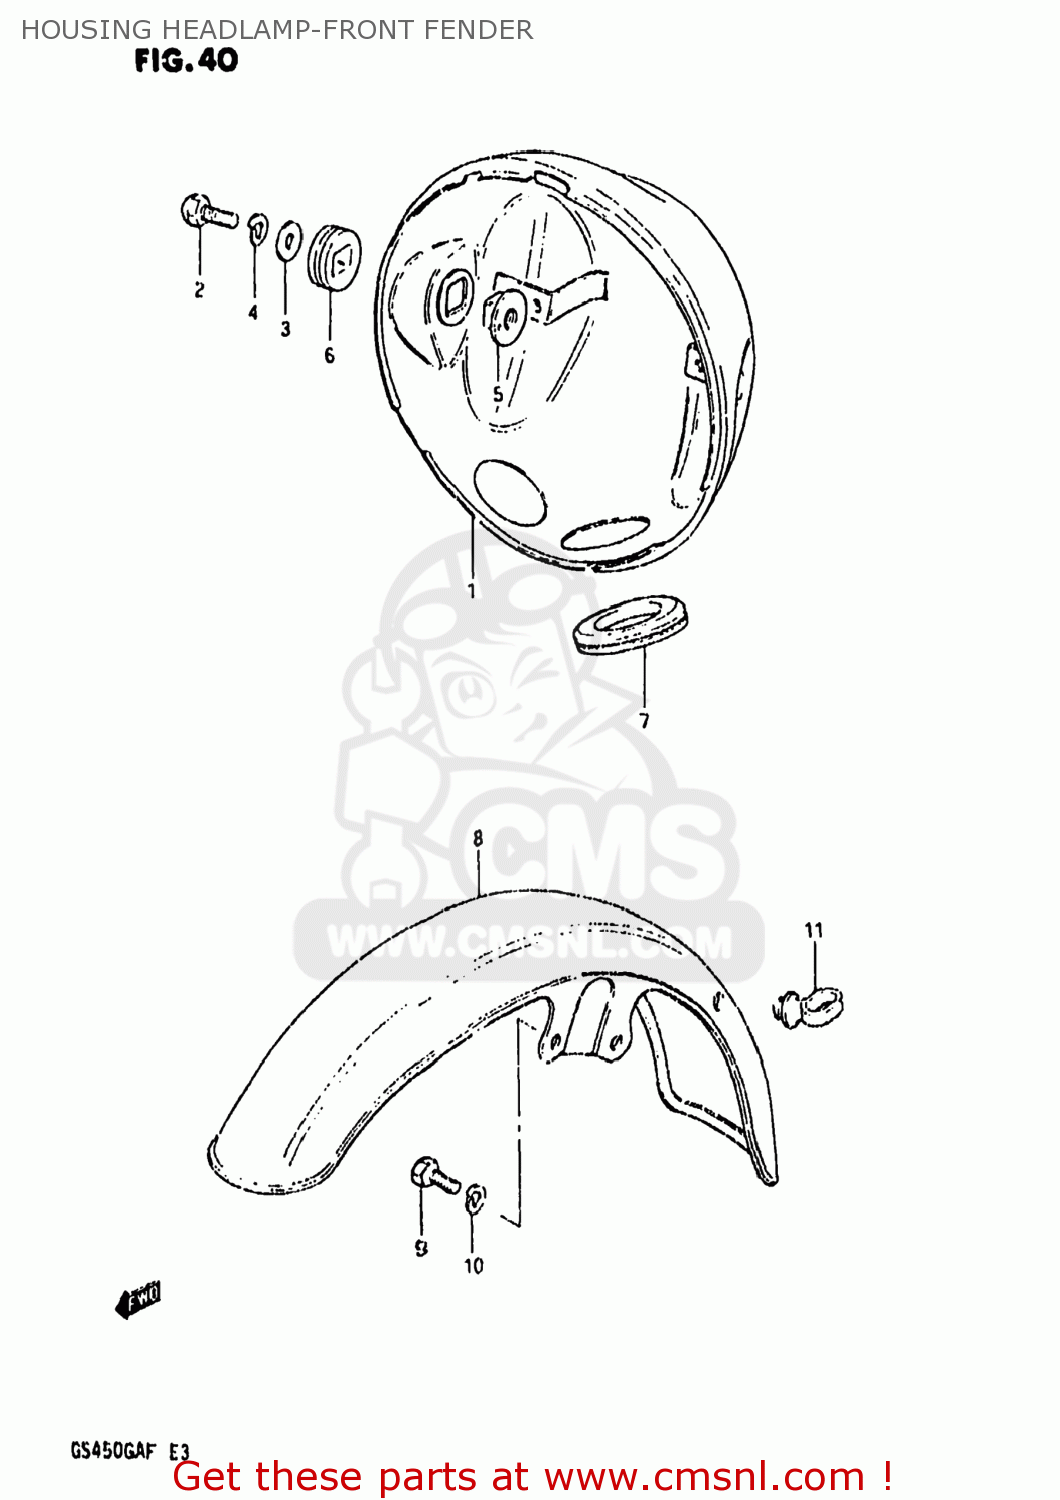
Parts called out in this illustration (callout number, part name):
1	HOUSING,HEADLAMP
2	BOLT
3	WASHER
4	LOCK WASHER
5	SPACER,HEADLAMP HOUSING
6	CUSHION,HEADLAMP HOUSING
7	GROMMET,HEADLAMP HOUSING
8	FENDER,FRONT
9	BOLT
10	LOCK WASHER
11	GUIDE,CABLE
